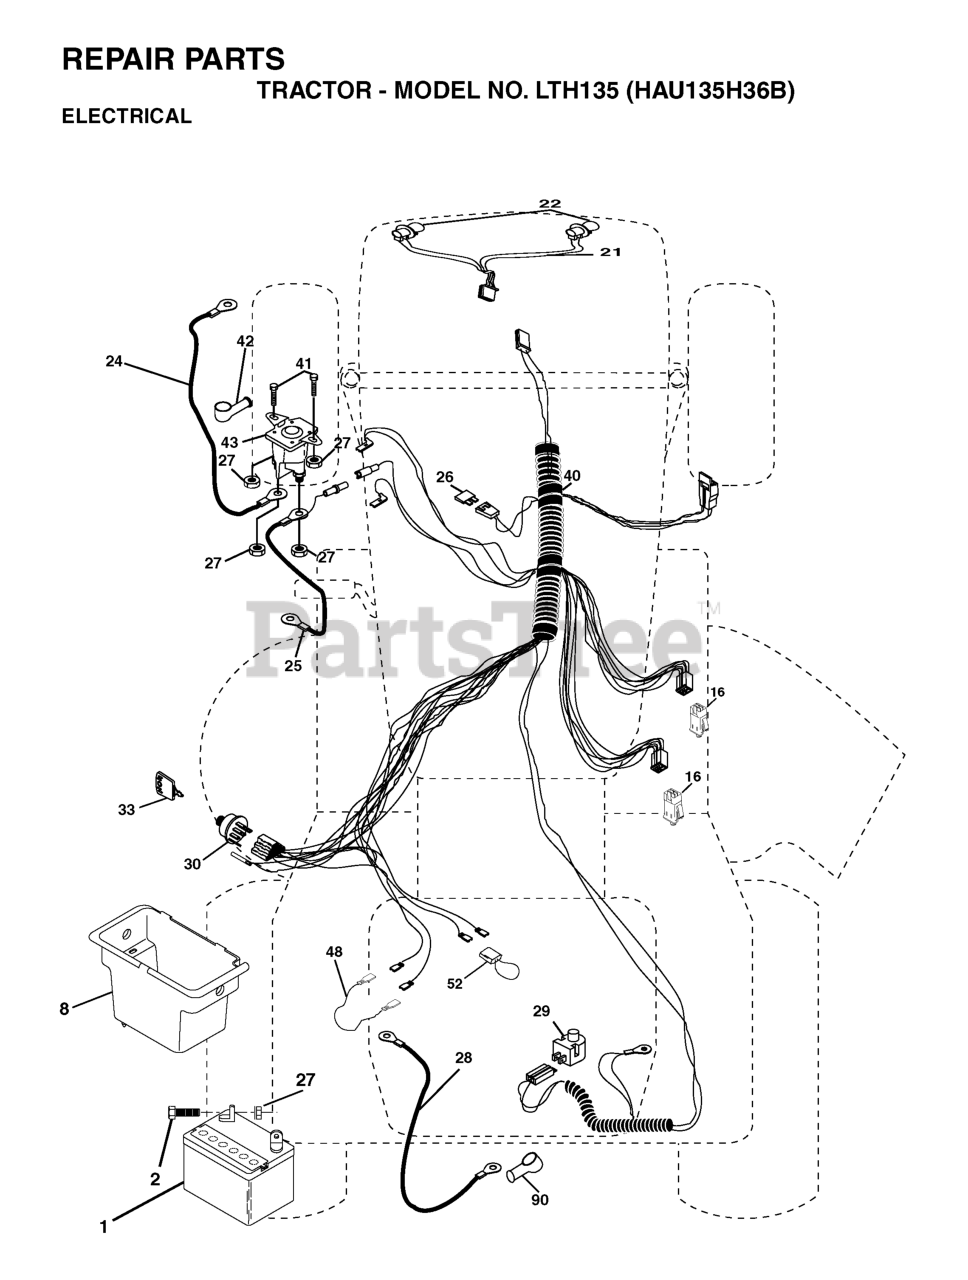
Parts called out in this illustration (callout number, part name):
1	Battery 12 Volt 25 Amp
2	BOLT.HEX.1/4.X.3/4.DICHROMATE
8	BOX.BATTERY.FENDER
16	SWITCH INTERLOOK PUSH-IN
21	HARNESS.ASM.LIGHT WSL
24	BATTERY CABLE GT
25	CABLE BATTERY
26	FUSE 20AMP
27	NUT
28	CABLE T
29	RP.SWITCH.PLUNGER.NC.GRAY
30	IGNITION SWITCH
33	KEY MLD GEN DELTA
40	HARNESS.IGNITION
41	BOLT
42	TERMINAL COVER
43	SOLENOID
48	ADAPTER.AMMETER
52	WIRE PROTECTION LOOP
90	COVER TERMINAL
